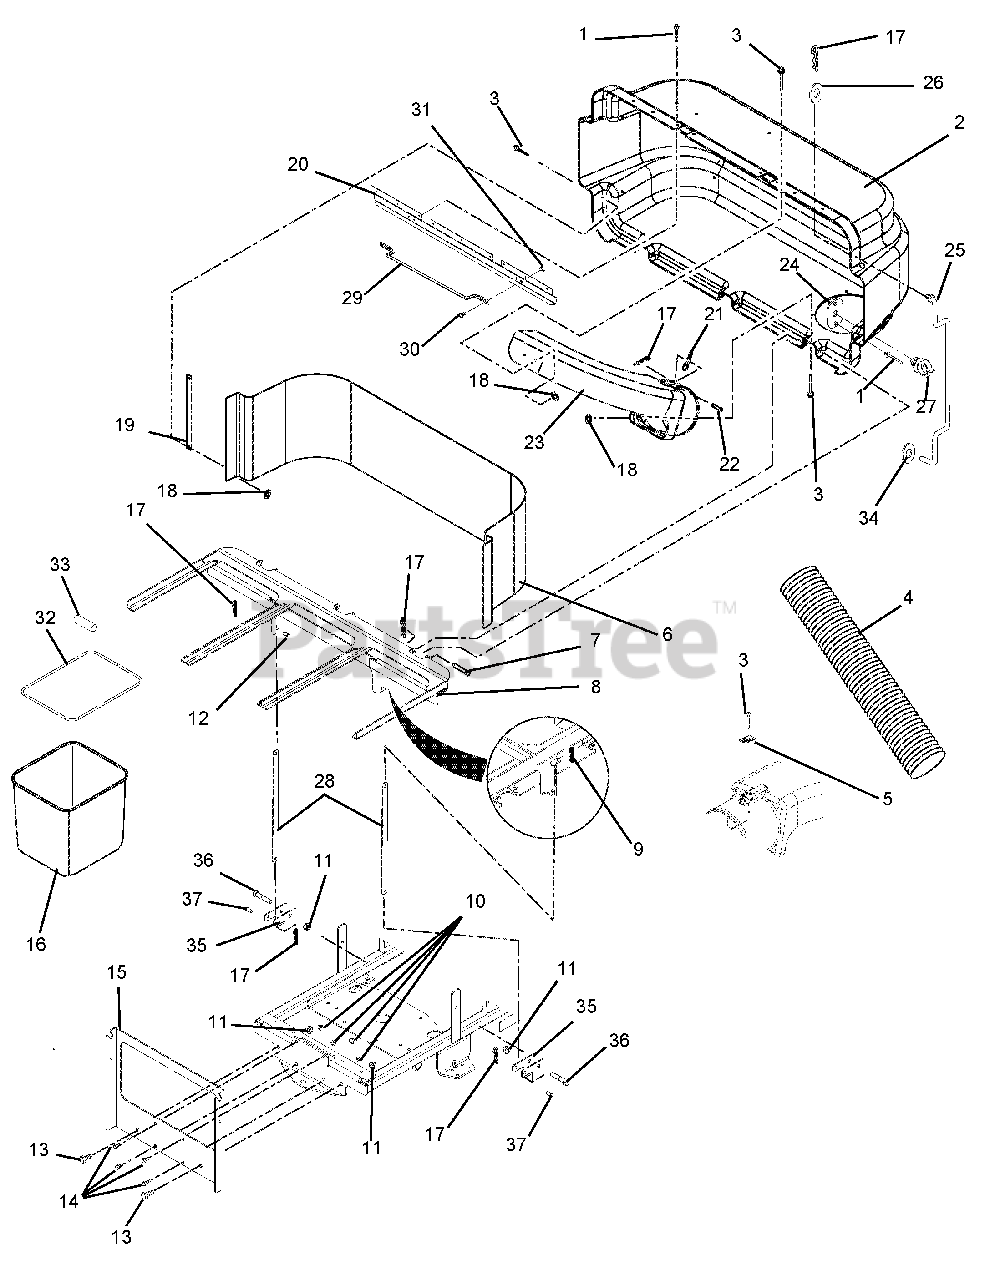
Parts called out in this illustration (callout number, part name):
1	Rivet-Pop .187 x .402
2	Cover, Bagger with Decal
3	Rivet-Pop .187 x .375
4	Hose, 7 x 38 Kanaflex 165 Clear
5	Thumb Latch
6	Screen, Bagger
7	Pin-Clevis .368/.373 x 3.25
8	Weldment, Bagger Frame
9	Pin, Hair, External- #16
10	Nut, .38-16 Nyloc Flange
11	Nut, .50-13 Nyloc Flange
12	Pin, Clevis .38 x .75
13	Bolt, Hex .50-13 x 1.00 Grade 5
14	Bolt, Hex .38-16 x 1.00 Grade 5
15	Mount, Rear Bagger
16	Bag, HVZ Mesh
17	Pin-Hair
18	Washer-Flat-Steel .219 x .50 x .049
19	Strap, Cover
20	Latch, Cover
21	Indicator, Flow
22	Pin-Clevis .31 x 2.62 Grade 5
23	Boot, Upper
24	Plate, Rod Clip
25	Prop-Rod, Bagger
26	Washer-Flat-Steel .046 x .812 x .065
27	Clip .38
28	Strap, Reinforcing
29	Bagger Handle
30	Bolt, Round Head Square Neck .25-20 x .75 Grade 5
31	Nut, Locking-Top-Flange .25-20
32	Frame, HVZ Bag
33	Hose, .38 x .50 x 3.00 Vinyl
34	Retainer, .38 Push-On
35	Clamp, HVZ Bagger Mount
36	Bolt, Hex .50-13 x 2.75 Grade 5
37	Pin, Clevis .373/.368 x 2.12
